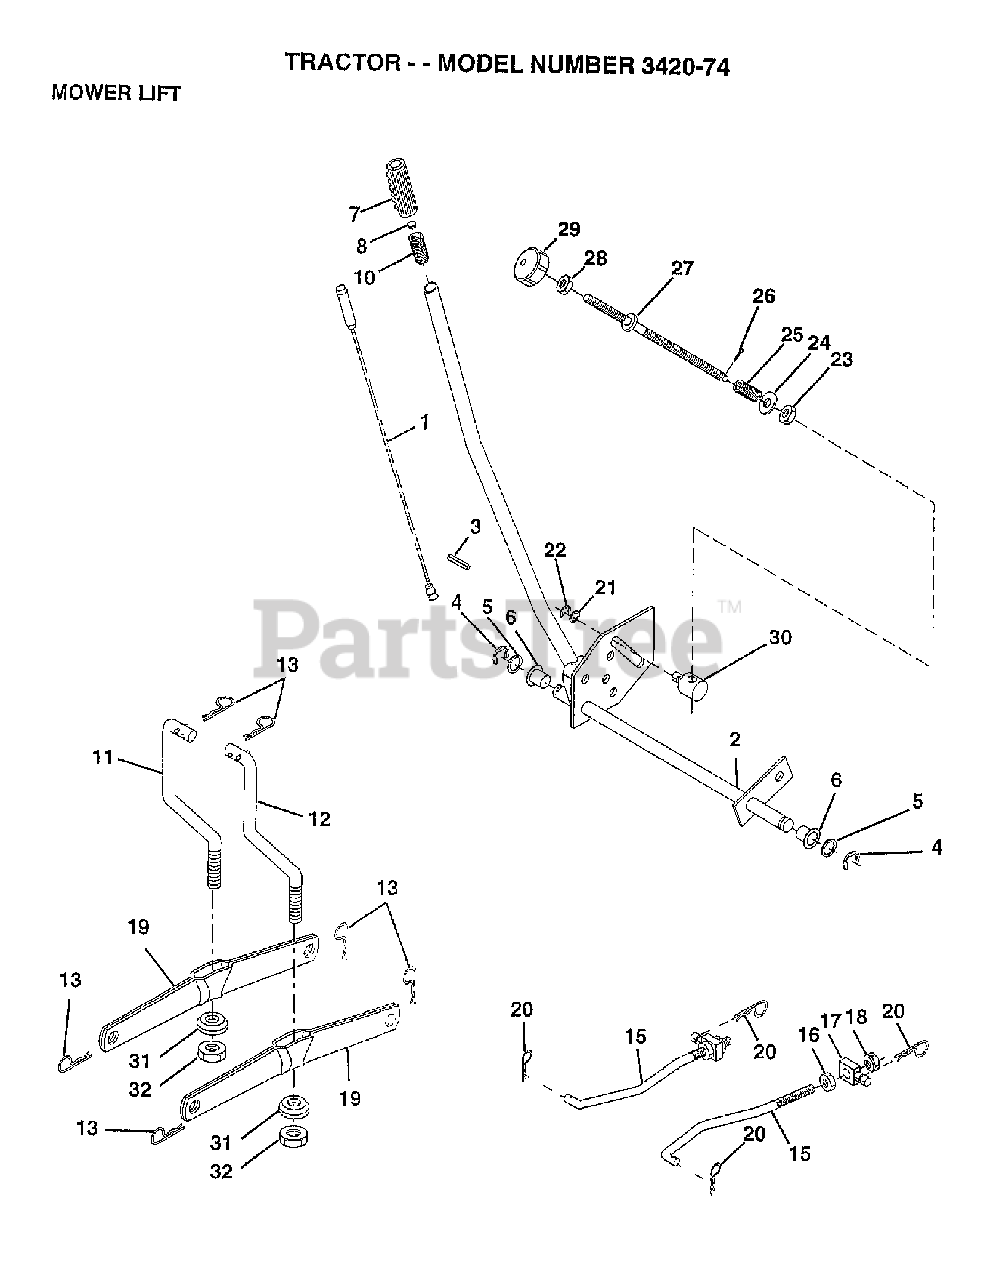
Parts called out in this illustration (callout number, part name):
1	WIRE.INNER.HANDLE.LIFT.LEVER
2	LIFT ARM ASSY
3	PIN GROOVE
4	RETAINING RING LT
6	BEARING.NYLON
7	GRIP
8	PLUNGER BUT KIT
10	SPRING, COMP T
11	LINK LIFT LH
12	Lift Link Assembly, RH
13	RETAINER SPRING
15	FRONT LINK
16	NUT.HEX.JAM.1/2-13
18	NUT.LK.W/WSH.1/2.
19	ARM.REAR.SUSPENSION
20	SPRING RETAINER
24	WASHER
25	SPRING.COMP.INF.H
27	ROD.LIFT.ADJUSTABLE
28	NUT
29	KNOB INF 3/8-16
30	TRUNNION
32	NUT CROWNLOCK 3/8-24
49	Flange Hex Lock Nut, 3/8-16
50	NUT PUSH M
